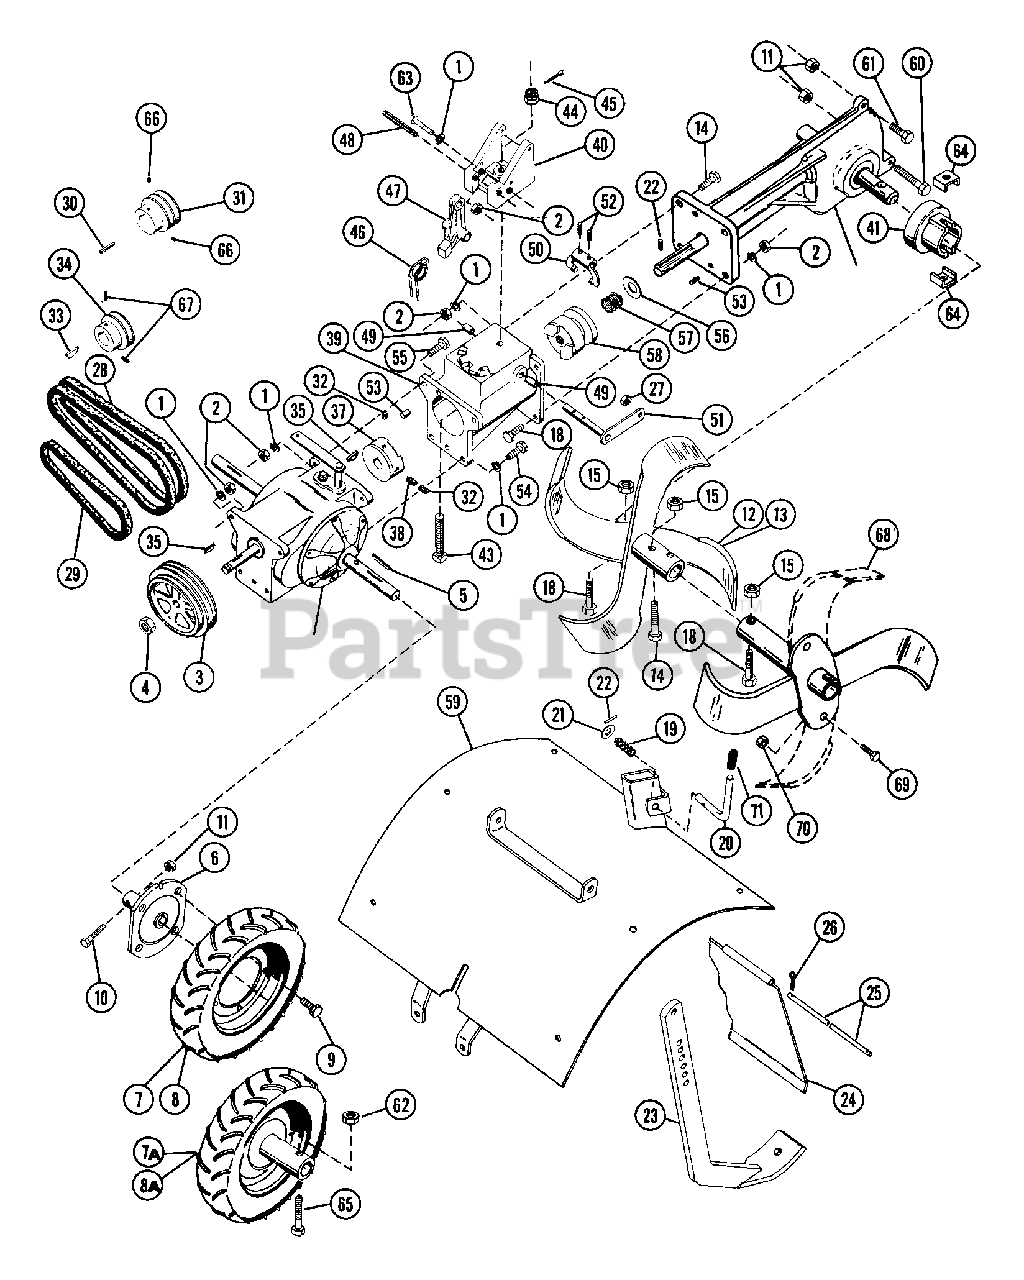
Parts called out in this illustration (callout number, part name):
1	WSHR-LK .375X.115 HVY PL
2	NUT-HEX .375-16
3	DRIVEN SHEAVE
4	NUT-LK-CTR .75-16 PL
5	KEY-FTHR .25X1.875X.25 SAE
6	WHEEL HUB
7	R H TIRE AND RIM ASSY
7	L H TIRE AND RIM ASSY
7	TIRE
7	WHL
8	RH TIRE & RIM ASSEMBLY
8	LH TIRE & RIM ASSEMBLY
8	TIRE
8	WHL
9	BLT-WHL .50-20X.75 GR5 PL
10	BLT-HEX .31-18X2.00 PL GR2
11	NUT-LK .312-18 GR A PL
12	R H INNER TINE SPOOL
13	L H INNER TINE SPOOL
14	BLT-HEX .38-16X1.75 PL GR2
15	NUT-LK-CTR .375-16 GR A PL
16	R H OUTER TINE SPOOL
17	L H OUTER TINE SPOOL
18	BLT-HEX .38-16X2.00 PL GR2
19	SG-COMP .045X.50X1.187
20	DEPTH REGULATING PIN
21	WSHR-FL-STL .38X.875X.083 PL
22	PIN-ROLL .125X1.00
23	DEPTH SHOE
24	TAILBOARD
25	TAILBOARD PIN
26	PIN COTR .09X.50 PL
27	NUT-LK-CTR .312-24 PL
28	V-BELT, SAE 380-RAW EDGE (SET)
28	V-BELT, 4L-WRAPPED
29	V-BELT, 4L-WRAPPED
30	KEY-SQ .25 X 1.25 X .25 SAE
31	ENGINE SHEAVE
32	SCR-SET .32-18X.38 SKHCUPNL OH
33	KEY-WDRF .125X.625X.250 SAE5
34	REVERSE SHEAVE
35	KEY-FTHR .188X1.25X.187 SAE
37	TILLER DRIVING JAW
38	SCR-SET .32-18X.50 SKHHOP OH
39	CLUTCH HOUSING
40	HANDLEBAR BRACKET
41	DUST CAP
43	SWIVEL BOLT
44	NUT-SL .50-13
45	PIN-COTR .12X1.0 PL
46	SG-TORS .109X.88X2.25
47	LATCH
48	PIN-ROLL .313X2.00
49	BSHG-SLV .500X.687X.500
50	CLUTCH FORK
51	TINE ENGAGING FORK SHAFT
52	PIN-ROLL .188X1.00
53	DOWEL PIN
54	BLT-HEX .38-16X1.25 PL GR 2
55	BLT-HEX .38-16X1.50 PL GR2
56	WSHR-FL-STL .755X1.375X.125
57	SG-COMP .080X.97X2.18 WLD14
58	TILLER JAW CLUTCH
59	TINE HOOD W/DECALS
60	BLT-HEX .31-18X3.50 PL GR2
61	BLT-HEX .31-18X1.25 PL GR2
62	NUT-LK .437-14 GR A PL
63	BLT-HEX .38-16X1.00 PL
65	BLT-HEX .44-14X2.00 PL GR2
66	SCR-SET .32-18X.38 SKHCUPNL OH
66	SCR-SET .25-20X.25 SKHCUPNY OH
67	SCR-SET .25-20X.38 SKHCUP OH
68	L H TURBO-TINE
68	R H TURBO-TINE
69	BLT-HEX .44-14X1.00 GR5
70	NUT-LK-TOP .437-14 GR C PL
